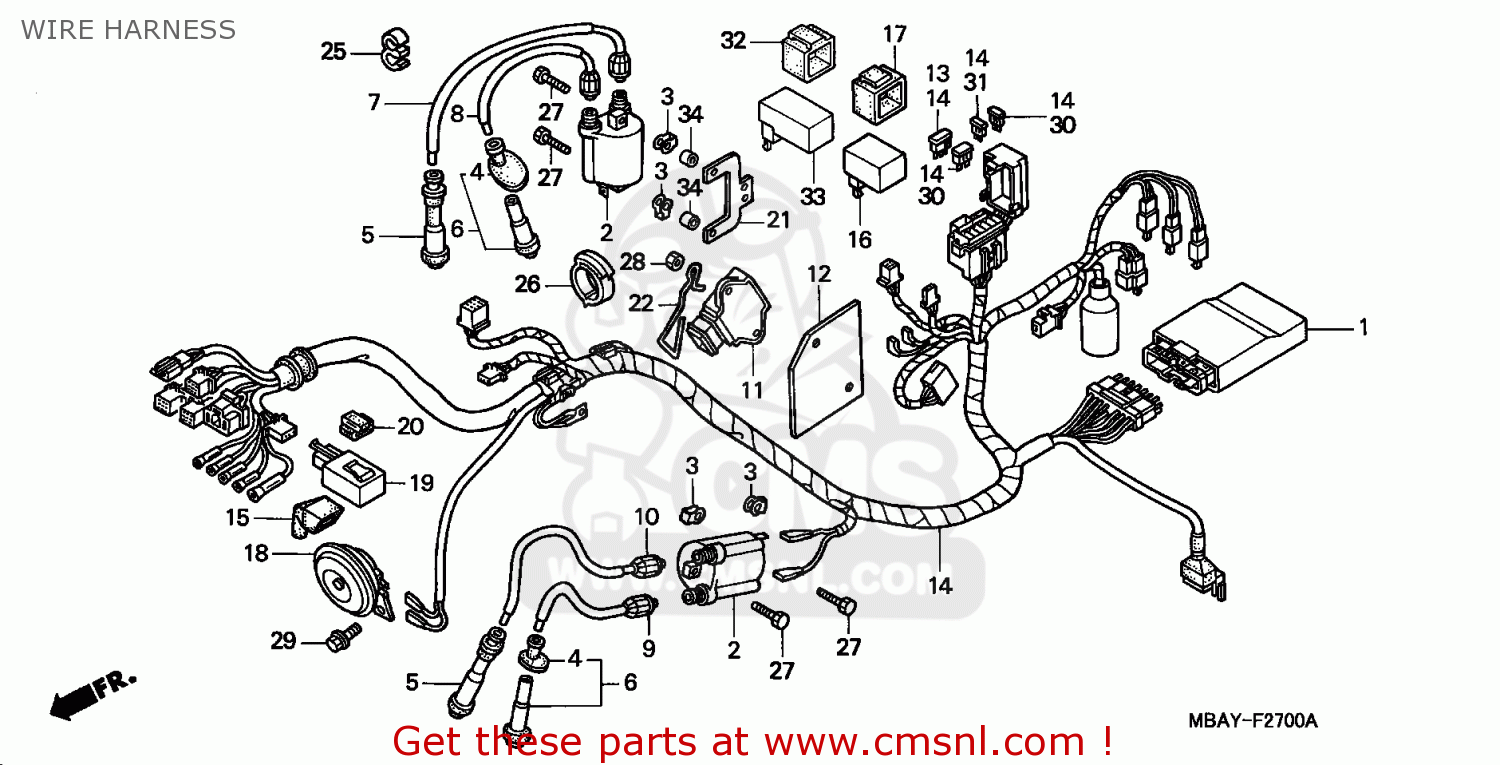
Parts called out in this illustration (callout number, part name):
1	UNIT COMP,SPARK
2	COIL COMP.,IGNITI
3	SPACER,IGNITION C
4	SEAL,PLUG CAP
5	CAP ASSY,NOISE SU
6	CAP,NOISE 2 SUPPR
7	CORD,HIGH/T FR-R
8	CORD,HIGH/T FR-L
9	CORD,HIGH/T RR-L
10	CORD,HIGH/T RR-R
11	REG RECT ASSY
12	SPACER,REG.RECT.
13	DIODE ASSY,3WAY
14	HARNESS WIRE
15	COVER,MAGNETIC SW
16	RELAY,FUEL CUT (S
17	SUSP,FUEL CUT
18	HORN COMP.(HIGH)
19	RELAY COMP.,WINKE
20	SUSP,WINKER,RELAY
21	STAY,IGN.COIL
22	GUIDE,REG.RECT
25	CLIP,H/T CORD
26	CLIP,WIRE HARNESS
27	BOLT,HEX.,6X20
28	NUT,FLANGE,6MM
29	BOLT,FLANGE,8X12
30	BLADE FUSE,MINI 10A
31	BLADE FUSE,MINI 15A
32	SUSP,C.D.I.UNIT
33	PL.LAMP CHECK UNI
34	COLLAR,6.5X11X3
